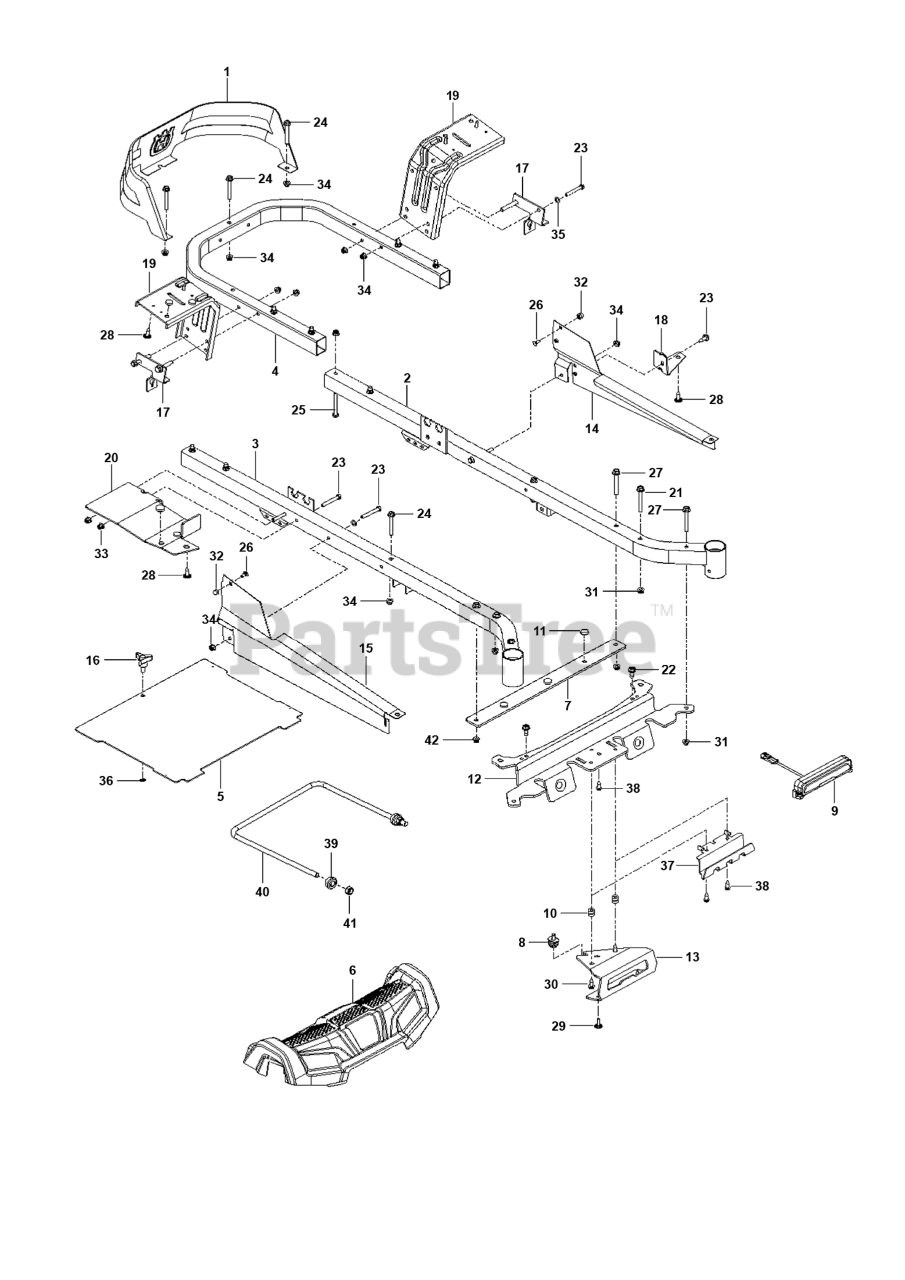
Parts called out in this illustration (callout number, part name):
1	GUARD.ENGINE.HUSQ.RZ.X498
2	FRAME.TUBE.RZ.MAIN.WELD.RH.ORG
3	FRAME.TUBE.RZ.MAIN.WELD.LH.ORG
4	TUBE.PNT.FRAME.RER.HUSQ.23".RZ
5	PLATE RZ FOOTREST HUSQVARNA OR
5	PLATE FOOT ORANGE X668
5	PLATE, FOOT W/DECALS RZ
5	PLATES
6	COVER.FOOTREST.REFRESH.ASM
7	FOOTREST.PLATE.SUPPORT.X431
7	SUPPORT.RZ.FOOTREST.PLATE.X43
8	SCREW.ADJ.ISOLATOR.BOLT.ASSY
9	LIGHT.ZTR.LED.ASM
10	GROMMET.RUBBER.PUSHIN
11	GROMMET.BUMPER
12	CROSS.PNT.MEMBER.BLK
13	BRACKET.SKIDPLTE.LED.RFRSHX417
14	COVER.RAIL.RH.RZ.X668
15	COVER.RAIL.LH.RZ.X668
16	KNOB W/STUD
17	BRKT ROD.BYPASS.EZT.X431
17	SUPPORT RZ REFRESH RH CONSOLE
18	SUPPORT.PNT.LH.CONSOLE.FRONT
18	SUPPORT RZ REFERSH LH CONSOLE
19	FENDER.SUPPORT.PNT.X431
20	SUPPORT.PNT.RH.CONSOLE.FRONT
21	BOLT SHOULDER,FLANGED,3/8-16X3
22	BOLT.5/16-18.THRD.ROLL.SHOULDR
23	BOLT.FIN HEX 5/16-18UNC X2 1/4
24	BOLT HEX
24	BOLT HEX 5/16-18 GR 5
25	BOLT.HEX.FIN.3/8-16 X 3.GR5
26	BOLT.CARRIAGE.5/16-18.7/16
27	HHFS 3/8-16 X 3 GRD 5 ZD
28	SCREW.#10 X 0.750.BOS
29	SCREW.#10 X 0.500
30	BOLT.5/16-18X1.25
31	NUT 3/8-16 HEX FLG NYLOC ZD
32	NUT ACORN,FLANGED,5/16-18
33	NUT LOCK HEX FLANGE 5/16-18
34	5/16-18 NYLOC FLANGE NUT
35	WASHER
36	WASHER 5/16"
37	SKID PLATE RZ REFRESH STANDARD
37	SKID.PLATE.PNT.RZ.REF.SIVER
38	BOLT.5/16HEX.WHS.HD
39	BUSHING SPHERICAL SUSP. FRONT
40	LINK, FRONT SUSP.
41	7/16-14 HEX NUT W/NYL RING ZD
42	SCREW.#10 X 0.500
